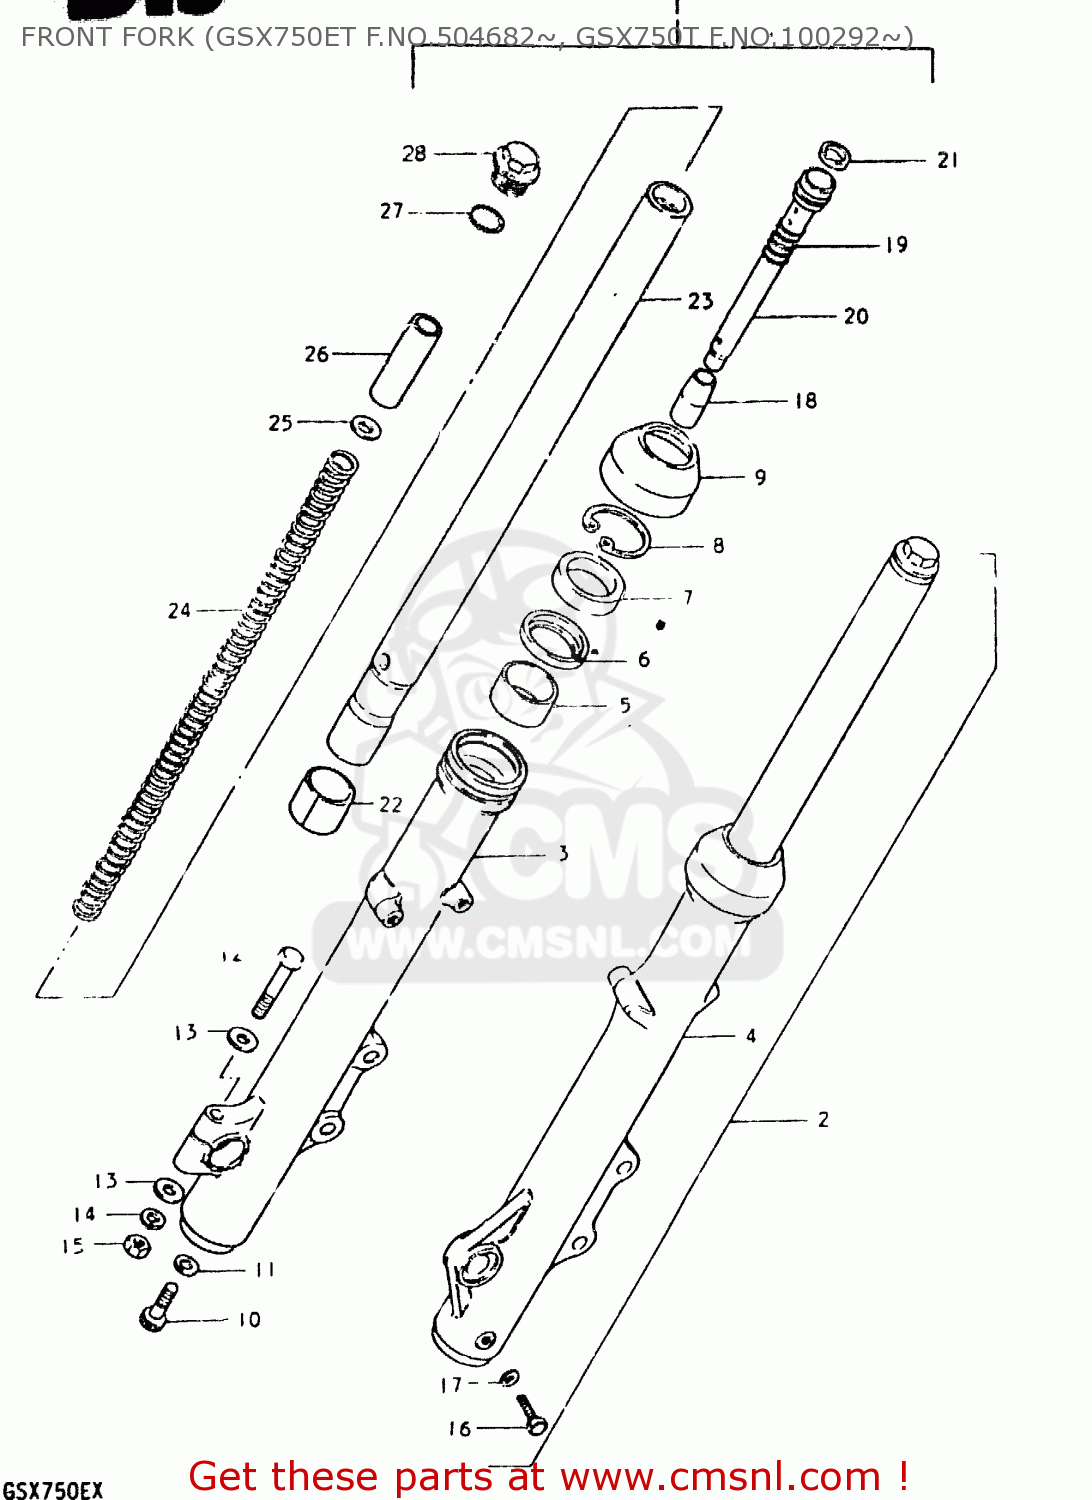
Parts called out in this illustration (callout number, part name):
1	DAMPER ASSY, RH
2	DAMPER ASSY, LH
3	TUBE,FORK,OUTER,RIGHT
4	TUBE,FORK,LEFT,OUTER
5	BUSH,GUIDE
6	SPACER,SEAL
7	OIL SEAL,FRONT FORK
8	CIRCLIP,FORK OIL SEAL
9	BOOT
10	BOLT(8X27)
11	GASKET (NAS)
12	BOLT 8X50
13	WASHER
14	LOCK WASHER
15	NUT
16	BOLT(6X8)
17	GASKET,DRAIN,PLUG (NAS)
18	PIECE,OIL LOCK
19	SPRING,FORK REBOUND
20	CYLINDER
21	RING
22	PISTON
23	TUBE,FORK,INNER
24	SPRING (L:557.8)
25	WASHER,SPRING
26	SPACER (L:74.4)
27	O-RING
28	CAP,INNER TUBE
